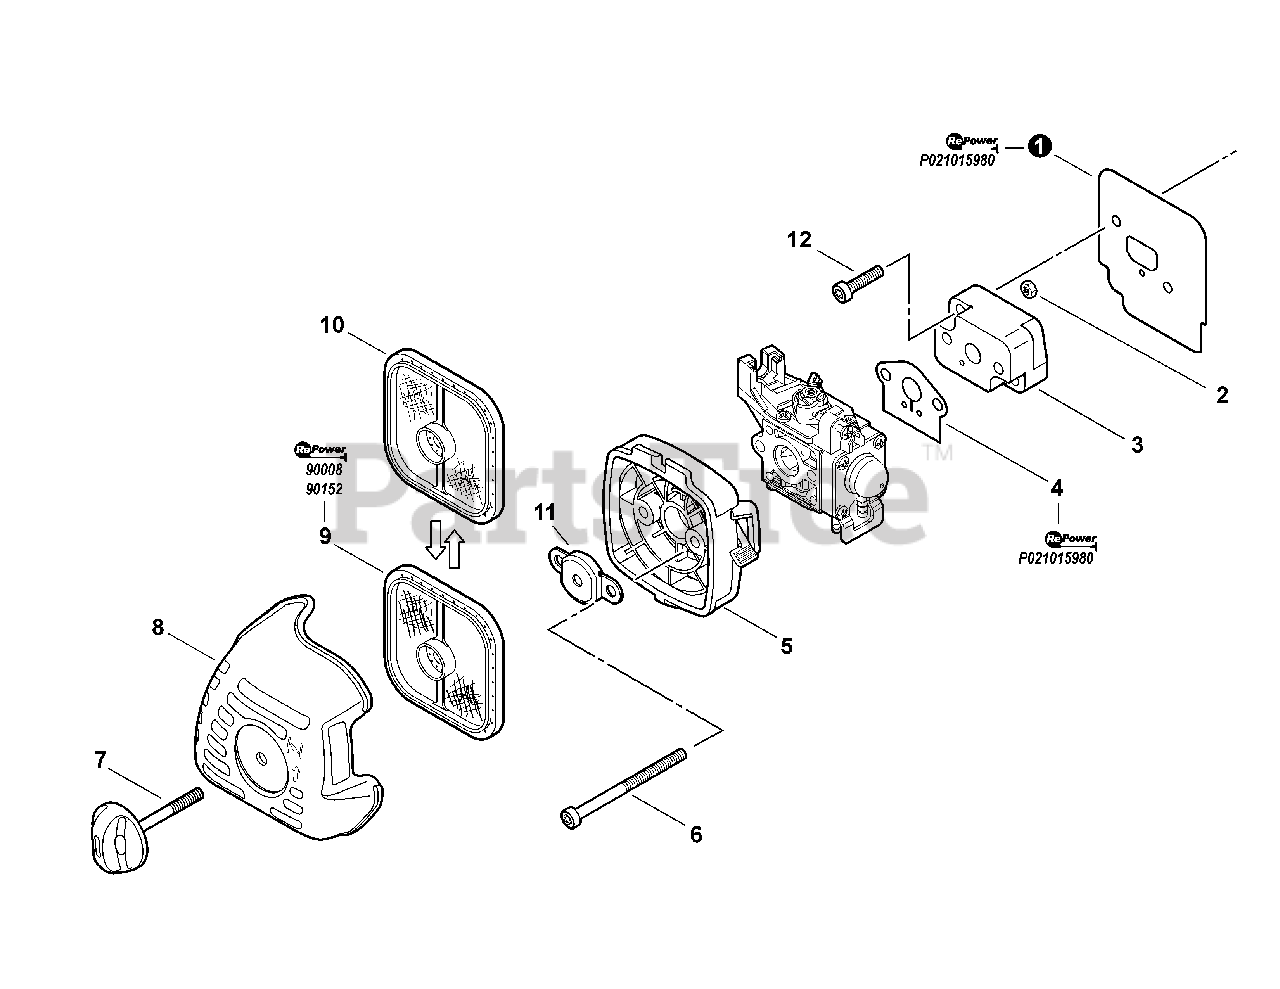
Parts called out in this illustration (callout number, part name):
1	HEAT SHIELD, INTAKE
2	NUT M5
3	INSULATOR, INTAKE
4	GASKET, INTAKE
5	CASE ASSY, AIR FILTER
6	BOLT, TORX 5×65
7	THUMBSCREW
8	COVER, AIR FILTER
9	FILTER, AIR - DOUBLE LAYER
10	FILTER, AIR - SINGLE LAYER
11	PLATE, PREVENT
12	BOLT, TORX 5×20
